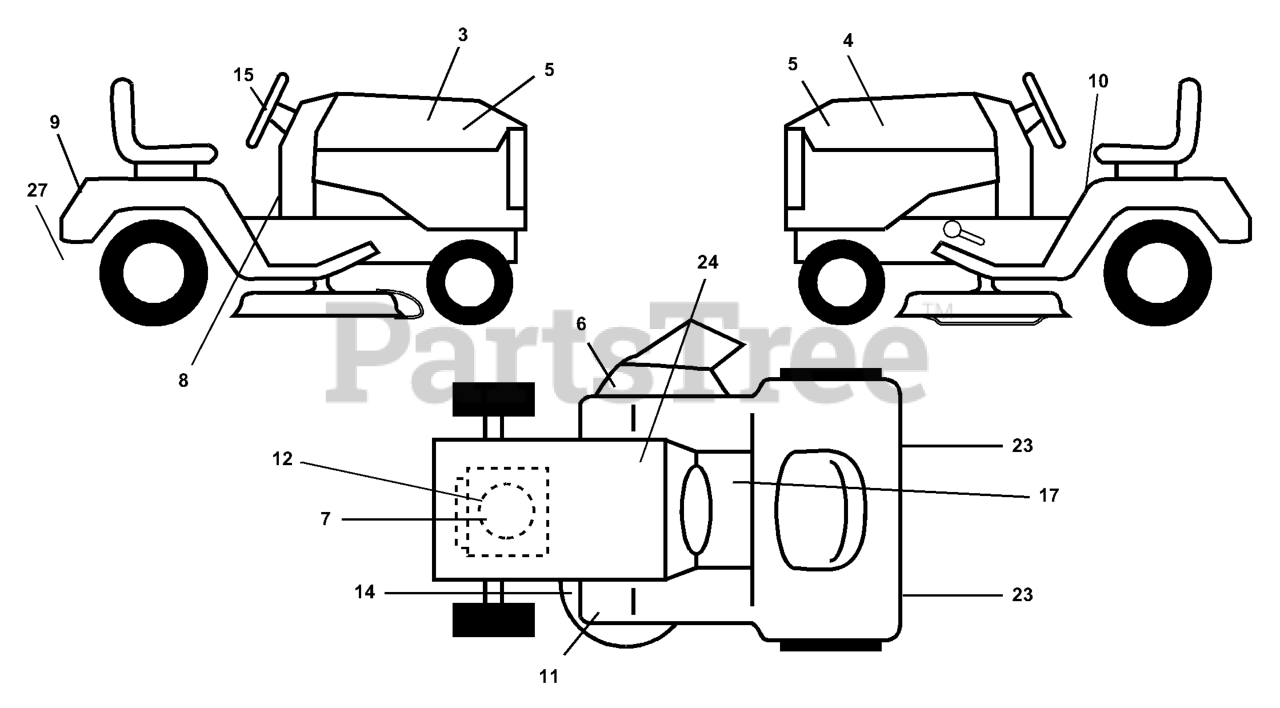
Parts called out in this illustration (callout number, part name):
3	DECAL, HOOD RH GTH2550
4	DECAL HOOD LH GTH2550
5	DECAL, HOOD SIDE
6	DECAL.WARN.KEEP.HAND.AWAY
7	DECAL, ENGINE HP
8	DECAL, DASH
9	DECAL, FENDER
10	DECAL FENDER DANGER
12	DECAL, ENGINE LOGO
14	DECAL V-BELT SCHEMATIC
15	DECAL.WHEEL.STEERING.HUSQ.PERM
17	DECAL PARK BRAKE
23	REFLECTOR-TAIL YT
24	DECAL BTRY SYMBOLS
27	DECAL D-BAR
27	DECAL HANDLE LIFT
